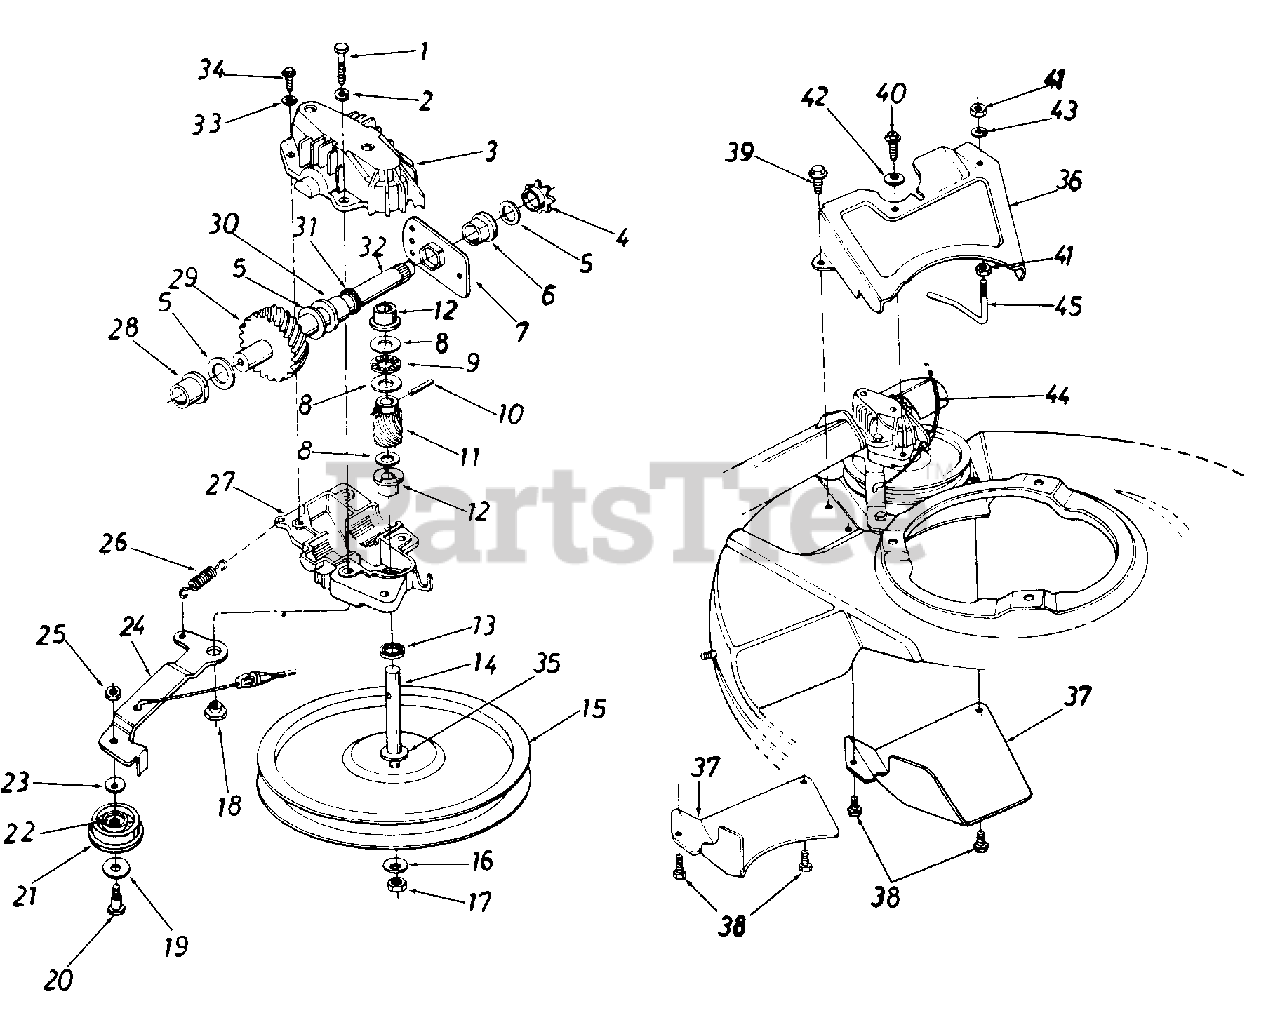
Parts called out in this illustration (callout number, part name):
1	Hex Bolt 1/4-20 x 1.25" Lg.
2	L-Wash. 1/4" I.D.
3	Upper Hsg. Half
4	#48 Sprocket 7 Tooth x 1/2 Pitch
5	Fl-Wash. 518" I.D. x .030
6	Hex Flange Brg. .631" I.D.
7	Hex Bearing Cup
8	Thrust Wash. .382" I.D. x .70" O.D.
9	Thrust Bearing .375" I.D. x .812" O.D.
10	Spring Pin Spir. 1/8" x .62" Heavy
11	11 Tooth Helical Gear
12	Flange Bearing
13	Oil Seal
14	Pulley-Transmission Shaft
15	Fl-Pulley 5.06" O.D.
16	Bell-Wash. .265" I.D. x .75"
17	Hex L-Nut 1/4-28 Thd
18	Shld. Spacer .375" Dia. x .170
19	Fl-Wash. .390" I.D. x 1.0"
20	Shld. Bolt .375" Dia. x .40"
21	Fl-Idler Plastic 1.50" Dia.
22	Needle Brg. .375" x .31
23	Bell-Wash. .265" I.D. x 75"
24	Idler Brk't. Ass'y.
25	Hex Patch L-Nut 1/4-28 Thd.
26	Extension Spring 1.12" Lg.
27	Lower Hsg. Half
28	Flange Bearing .566 Dia.
29	33 Tooth Helical Gear
30	Flange Bearing .629 Dia.
31	Oil Seal .625 Dia.
32	Gear Sprocket Shaft
33	L-Wash. #10 I.D.
34	Hex B-Tap Scr. #10 x .62"
35	Hex Washer .26" x .88"
36	Transmission Belt Guard
37	Belt Cover
38	Hex B-Tap Scr. 1/4 x .38" Lg.
39	Hex AB-Tap Scr. 1/4 x .50" Lg.
40	Hex B-Tap Scr. 1/4 x .62" Lg.
41	Hex Nut 1/4-20 Thd *
42	Bell-Wash. .265" I.D. x 75"
43	L-Wash. 1/4" I.D.
44	S.P. Cable-50" Lg.
45	S.P. Belt Guard
